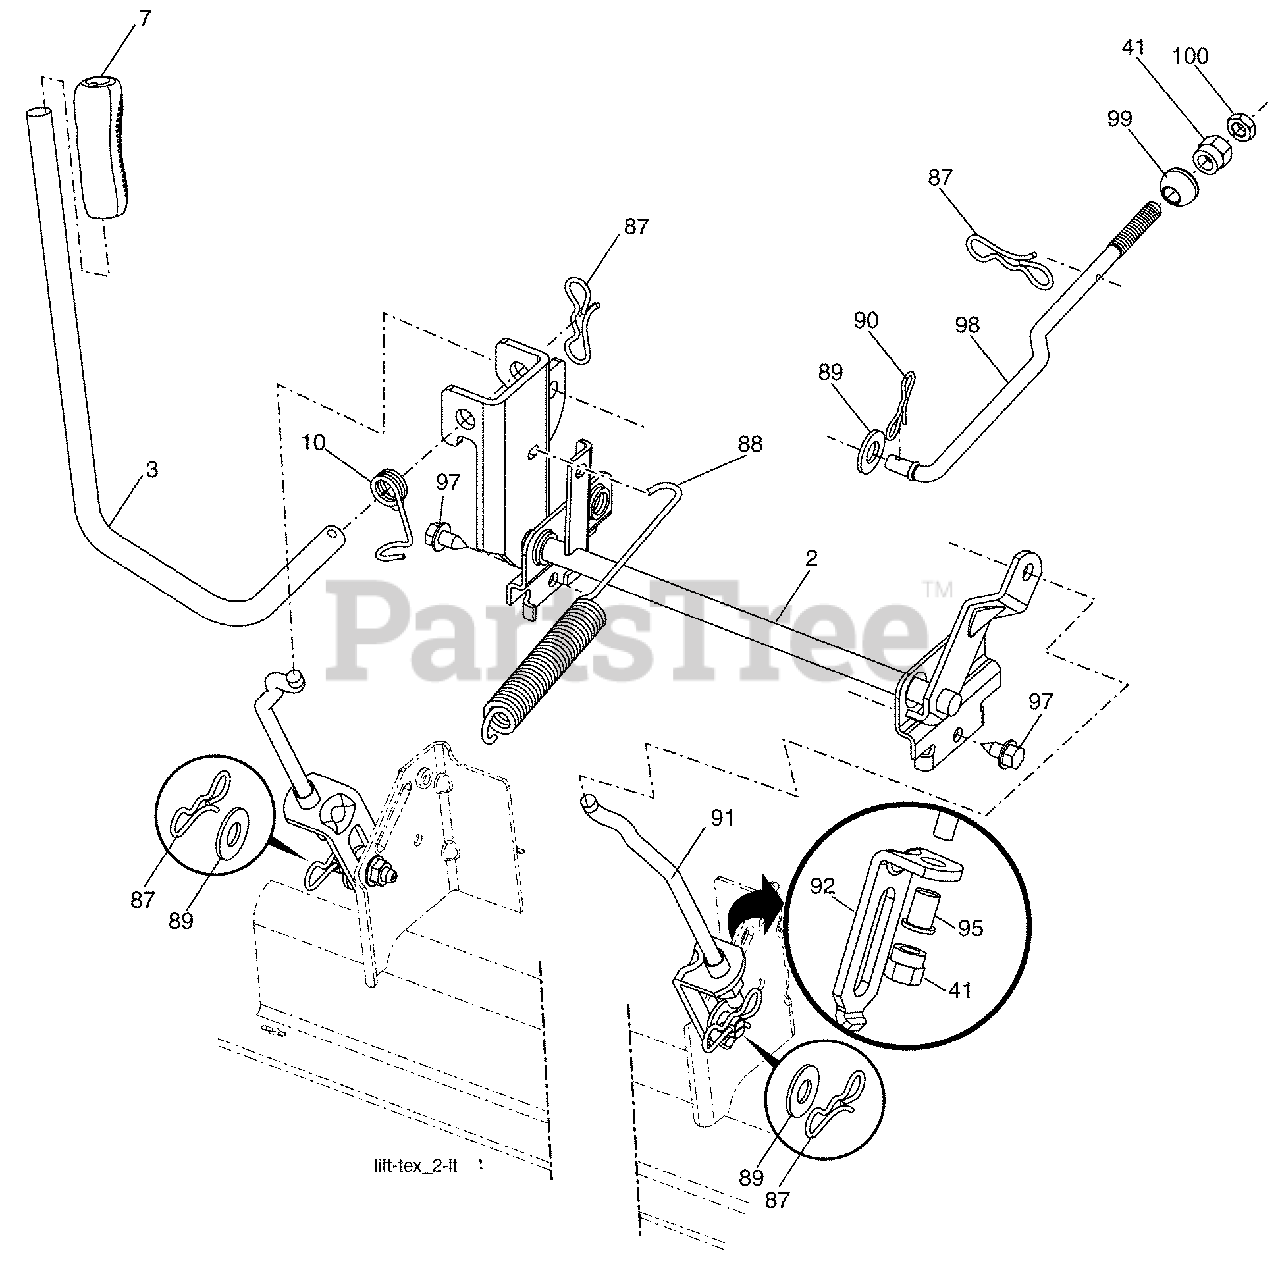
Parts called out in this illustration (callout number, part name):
2	Shaft Asm., Lift
3	Lever Asm., Lift Rh
7	Grip, Lever
10	Spring Torsion
41	Nut, 7/16-20
87	Pin Cotter 7/16 Bow Tie Lock
88	Spring Lift Assist
89	Washer Clear Zinc
90	Pin Cotter 5/16 Bow Tie Lock
91	Link Lift Susp Mower Rear
92	Bracket Connect Link Lift
95	Bushing Alignment Link Lift
97	Screw 3/8-16 x .75 Smgml Tap/R.Z
98	Link Lift Susp. Front Mower
99	Bushing Spherical Susp Front
100	Nut Hex Jam ASF 7/16-20 unf
